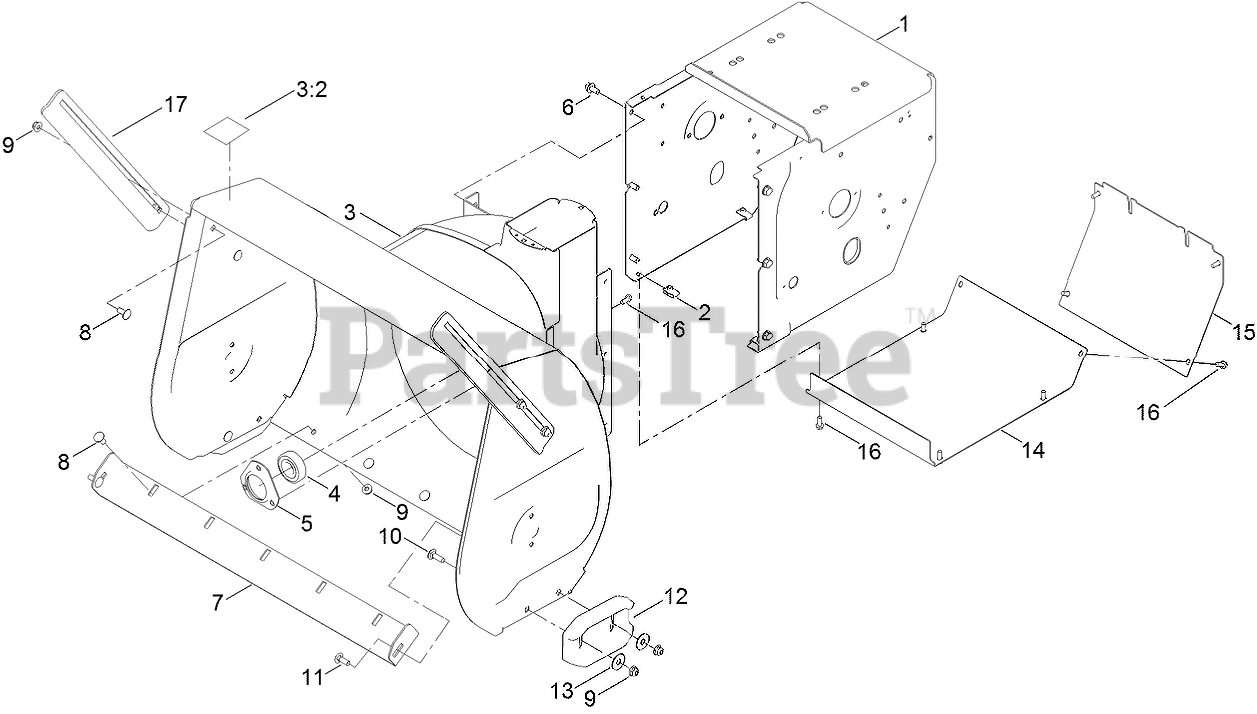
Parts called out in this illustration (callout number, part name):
1	FRAME-TRACTION
3	AUGER HOUSING ASM
3:2	DECAL-DANGER
4	BEARING-BALL
5	RETAINER-BEARING
6	SCREW-HWHTF
7	BLADE-SCRAPER
8	BOLT-CARR
9	NUT-HF
10	BOLT-CARR
11	BOLT-CARR
12	SKID-CAST
13	WASHER-FLAT
14	COVER-BOTTOM
15	COVER-REAR
16	SCREW-HWH
17	BREAKER-DRIFT, SIDE
